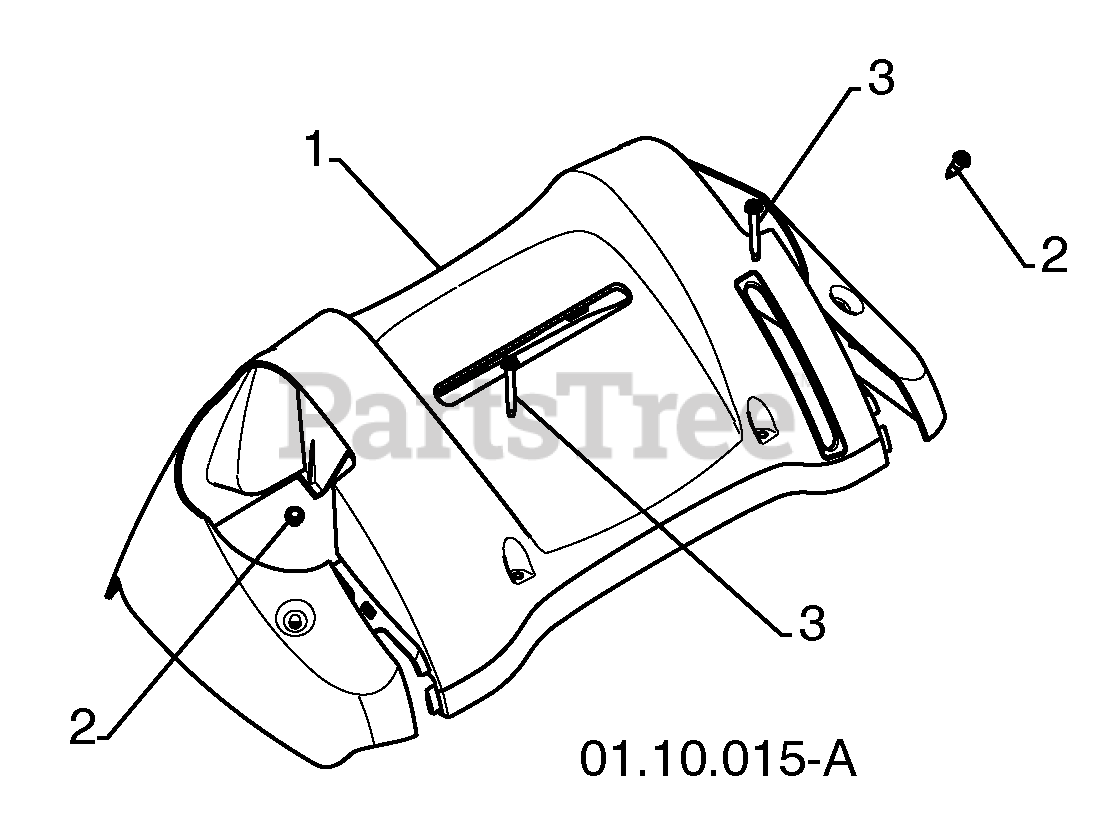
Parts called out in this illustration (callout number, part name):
1	CONSOLE PANEL
2	SCREW 10-24 X .625
3	SCREW 10-24 X 1.25
